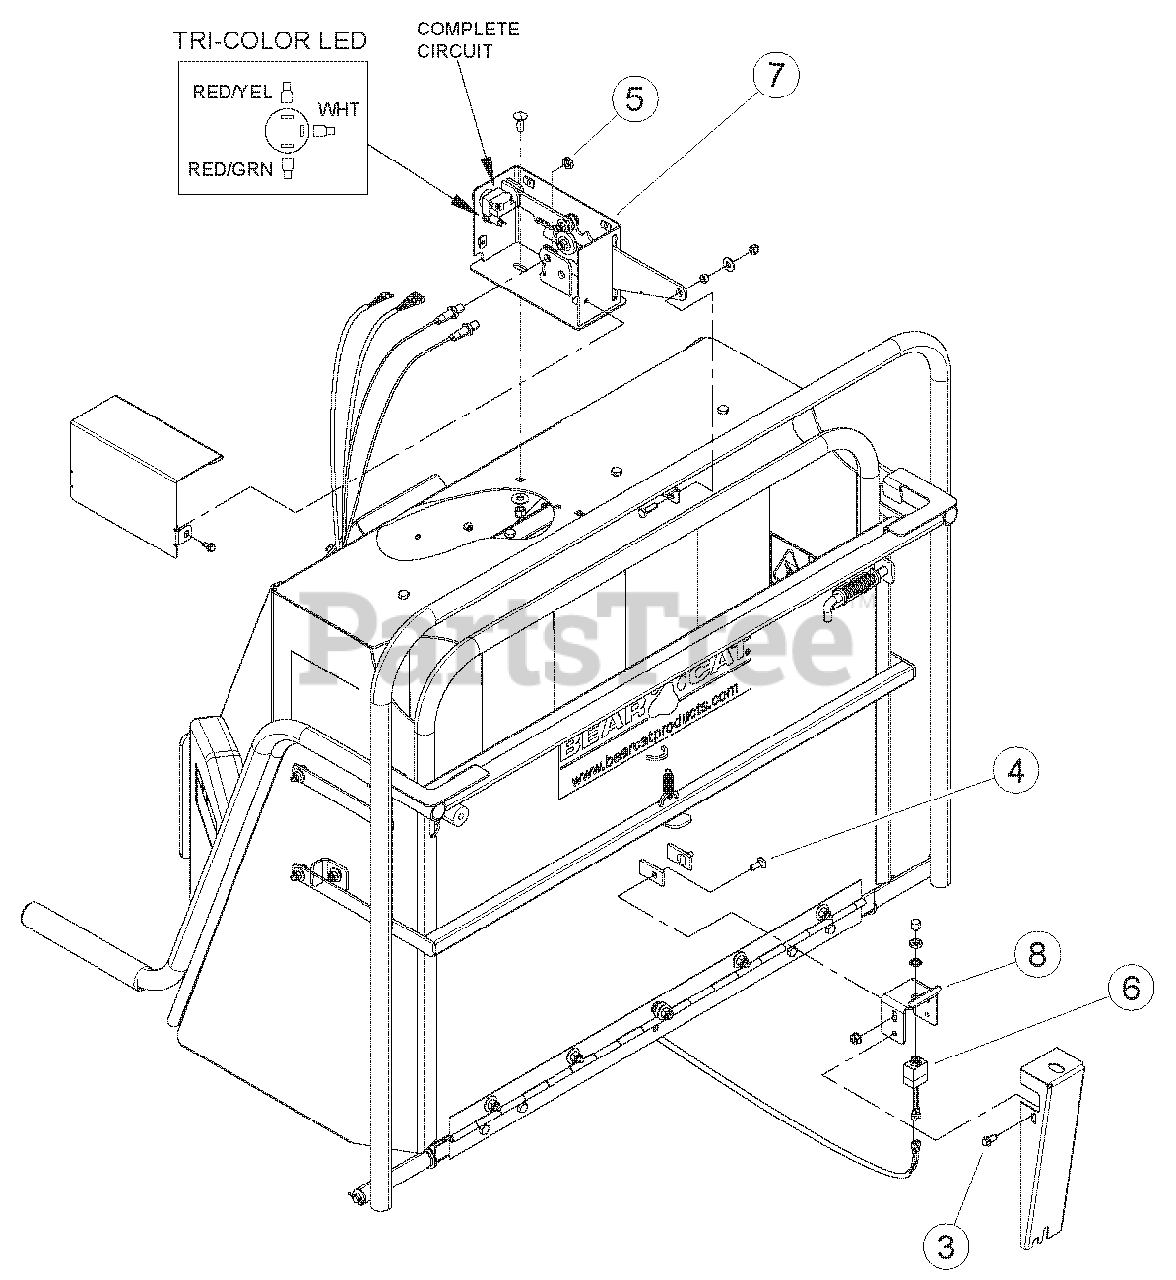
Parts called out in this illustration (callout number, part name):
1	CONNECTOR, 1/4 QD FEMALE
2	CONNECTOR, 1/4 QD MALE
3	SCW,11/32*7/8 HWH AB THREAD ZP
4	BOLT,CARR 5/16*7/8" GR5 NC ZP
5	NUT, 5/16-18 NYLOCK-FLANGE
6	SWITCH, MOMENTARY IP67 NORMALLY ON
7	ASSEMBLY, SWITCH BOX
8	BRACKET, SWITCH
